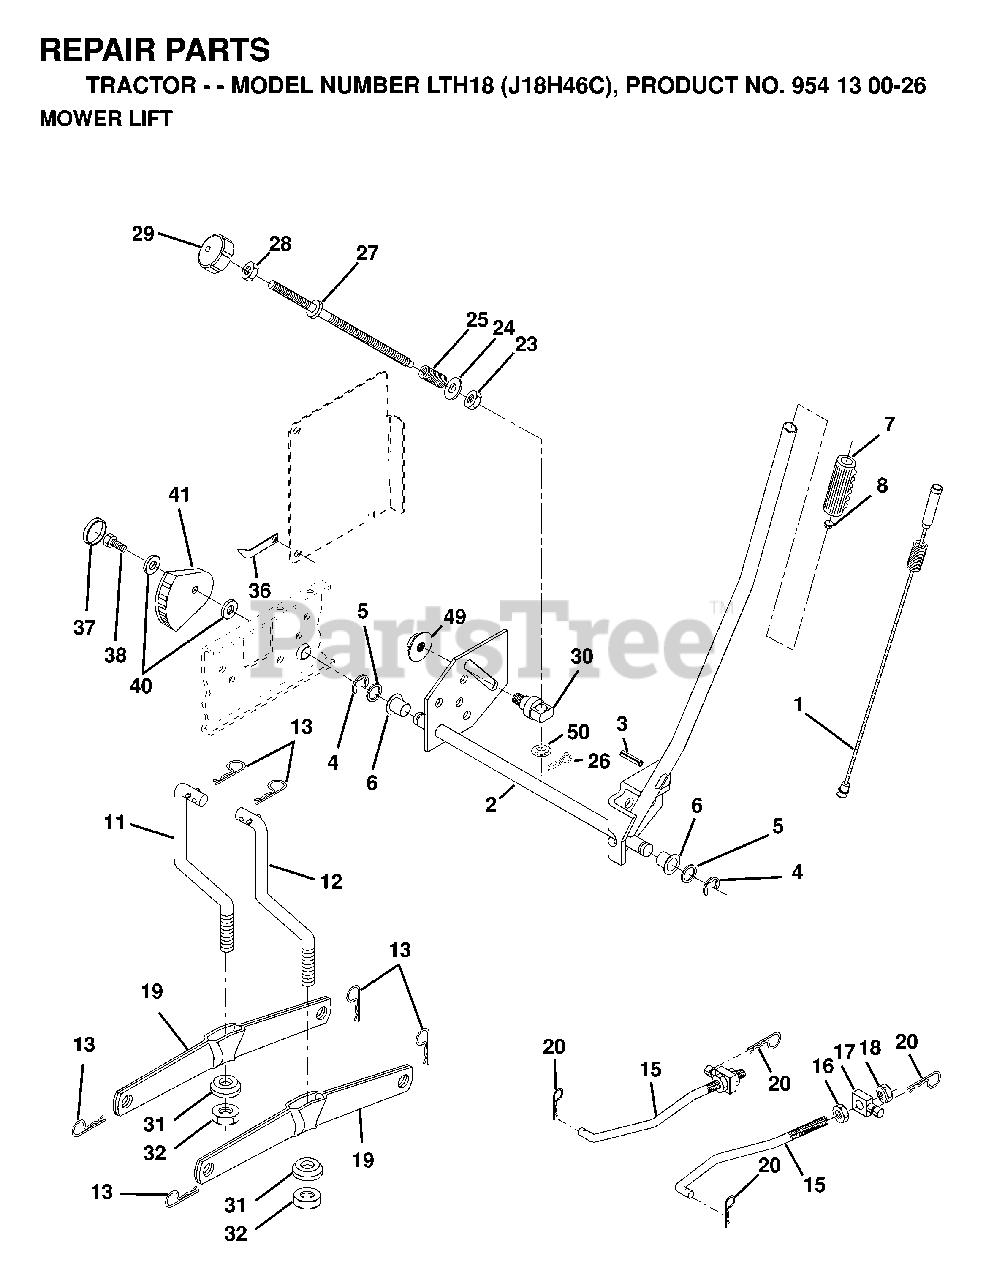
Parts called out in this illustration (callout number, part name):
1	WIRE ASM INNER W/ PLUNGER LT
2	SHAFT ASM R HANDLE
3	PIN GROOVE
4	RETAINING RING LT
6	BEARING.NYLON
7	GRIP
8	PLUNGER BUT KIT
11	LINK LIFT LH
12	LINK LIFT RH
13	RETAINER-SPRNG RB
15	FRONT LINK
16	NUT
17	TRUNION
18	NUT LTV
19	ARM.REAR.SUSPENSION
20	SPRING RETAINER
25	SPRING**
26	COTTER PIN
27	ROD ADJ LIFT
28	NUT
29	KNOB INF 3/8-16
31	BEARING PIVOT
32	NUT CROWNLOCK 3/8-24
36	POINTER, HEIGHT INDICATOR
37	PLUG,HOLE
38	SCREW
41	IND. HEIGHT STLT
49	NUT
50	NUT PUSH M
